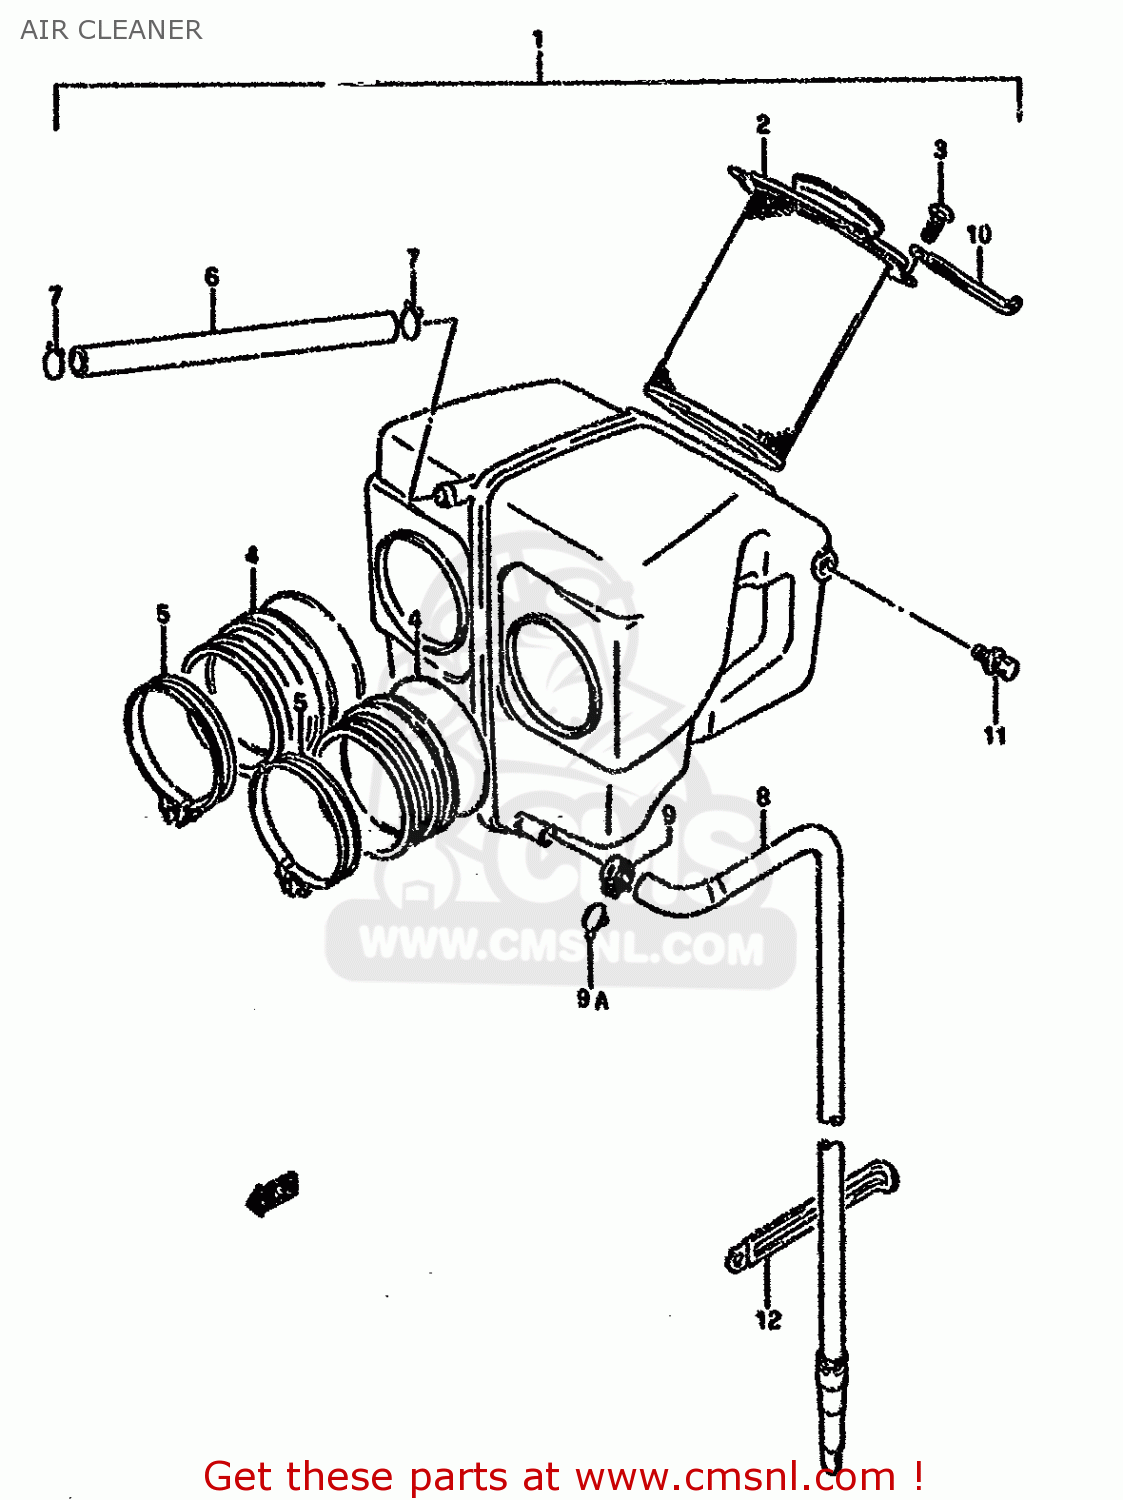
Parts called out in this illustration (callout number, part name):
1	CLEANER ASSY,AIR
2	FILTER ASSY
3	SCREW
4	TUBE,OUTLET
5	CLAMP
6	HOSE(11X15X600)
7	CLIP
8	TUBE,DRAIN
9	CLAMP
9A	CLIP
10	CLAMP
11	VIS
12	CLAMP
